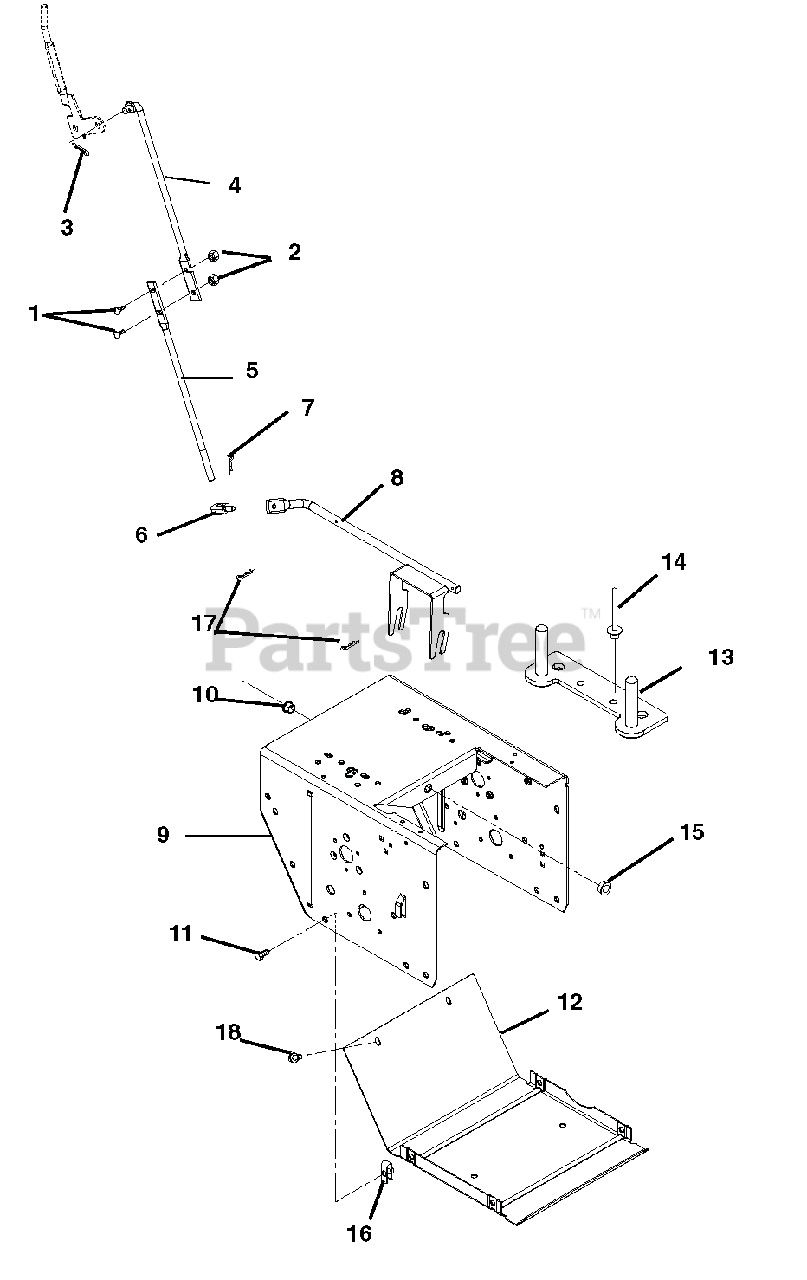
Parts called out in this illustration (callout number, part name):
1	@BLT-RDHDSQNK .25-20X.75 G5YZ
2	@NUT-LK-TOP-FLG .25-20 YWZC
3	PIN-HAIR, ENDRIES #25 YWZC
4	ROD, SHIFT-UPPER
5	ROD, SHIFT-LOWER
6	PIVOT,SHIFT ROD .375-16(TRUNN)
7	PIN-HAIR, ENDRIES #25 YWZC
8	ARM, SHIFT-WELDMENT
9	FRAME, MAIN
10	BUSHING, POLYLINER-.50 SPLIT
11	BLT-HEX .25-20X.75 HWH YZ GR5
12	COVER, BOTTOM
13	STRAP, ENGINE BOLT-LARGE BRIGG
14	RVT-POP .187 YZ
15	BUSHING, POLYLINER-.50 SNAPIN
16	NUT-RTNR .25-20X.56
17	CLIP, SPRING
18	SCR-TAP .25-20X.50 HWH TR YWZ
